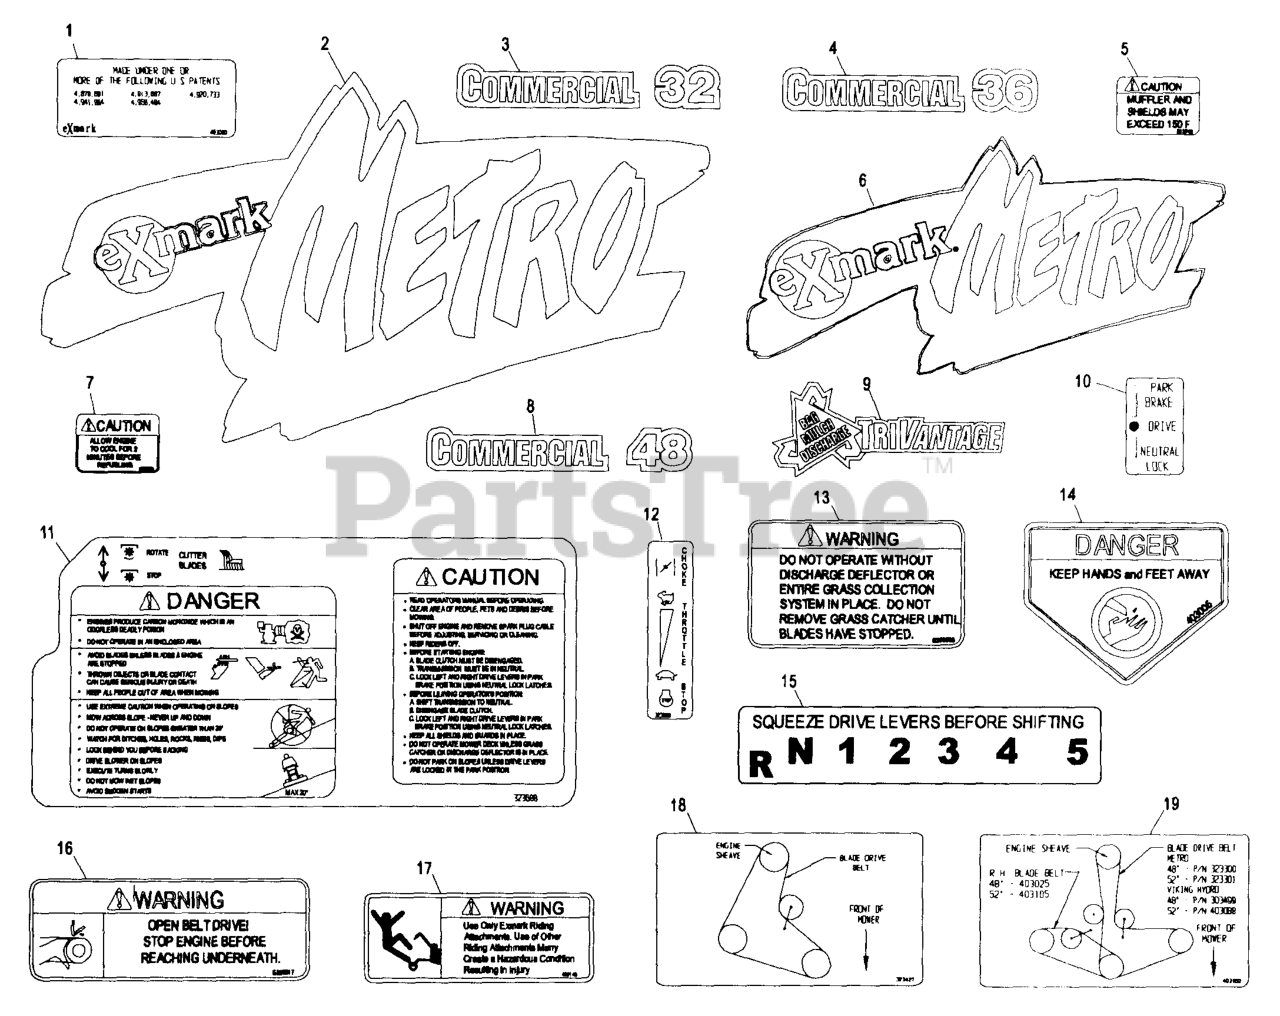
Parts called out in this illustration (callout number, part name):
3	DECAL,COMMERCIAL 32
4	DECAL,COMMERCIAL 36
8	DECAL,COMMERCIAL 48
10	DECAL,NEUTRAL/BRAKE
13	DECAL-WARNING, DISCHARGE
14	DECAL-DANGER
15	DECAL,SHIFTER
16	DECAL,BELT DRIVE
17	DECAL,SULKY WARNING
18	DECAL,BELT ROUTING 32/36
